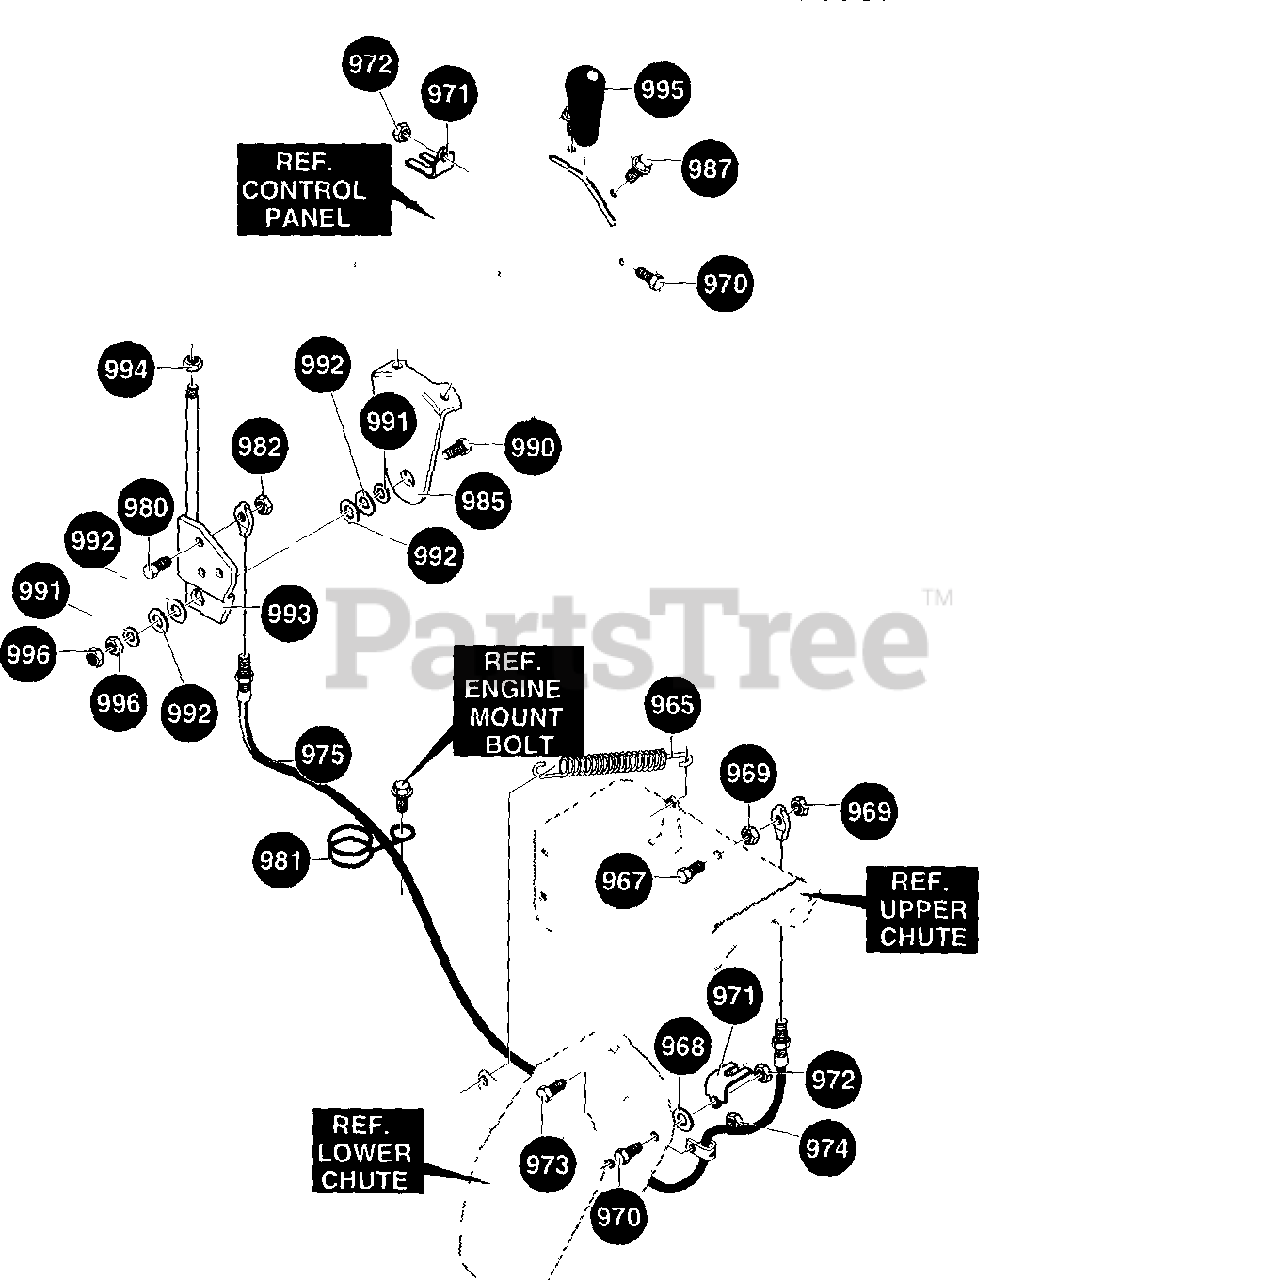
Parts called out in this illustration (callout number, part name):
965	SPRING, TENSION
967	SCREW, 1/4-20 X 1.00
968	FLATWASHER .344 X .69 X.065
969	NUT, 1/4-20 REGHEXCTRLK
970	SCREW, 5/16-18 X .75
971	BRKT, CABLE
972	NUT, 5/16-18
973	SCREW, 10-24 X.38
974	NUT, #10-24 HEXNYLLK
975	CABLE, CHUTE CONTROL
980	SCREW, 1/4-20 X .75 HHC
981	WIRE, FORM
982	NUT, 1/4-20 REGHEXCTRLK
985	BRACKET, SPD CONTROL
987	SCREW, 5/16-18 X .50
990	SCREW, 3/8-16 X 1.75
991	FLATWASHER .406 X .81 X .065
992	WASHER, SPRING
993	HANDLE, ASSY
994	NUT, 3/8-16
995	HANDLE 3/8-16
996	NUT, 3/8-16 HEXNYL
